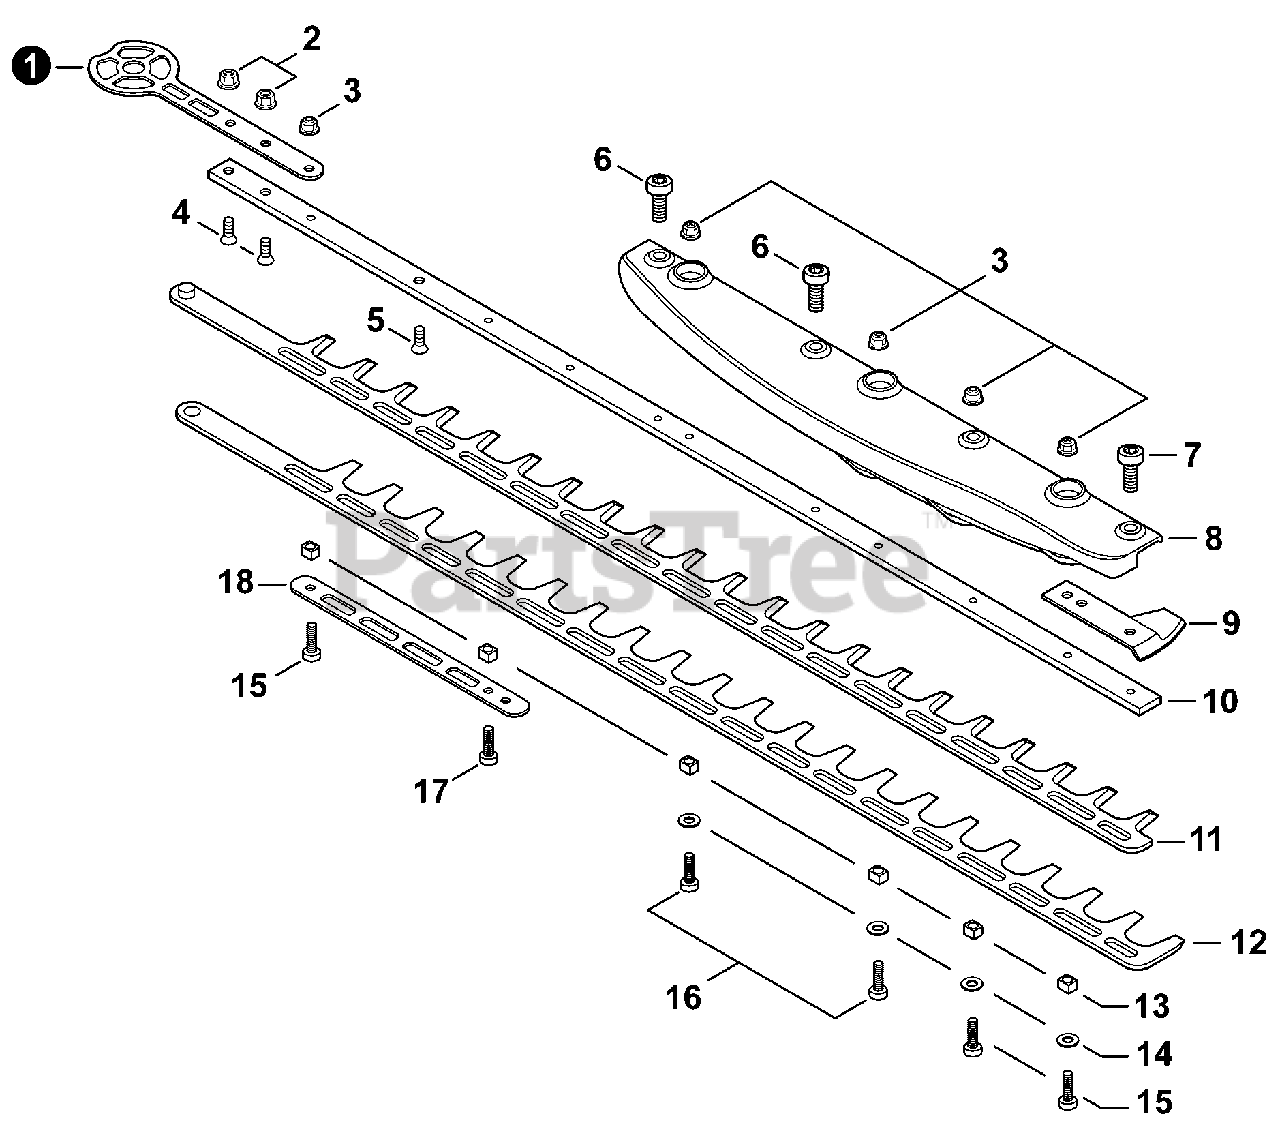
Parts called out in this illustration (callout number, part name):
2	NUT, FLANGE M6
3	NUT, FLANGE M5
4	BOLT 6×30
5	BOLT 6×25
6	BOLT, TORX 5×8
7	BOLT, TORX 5×10
8	DEFLECTOR, DEBRIS
9	GUARD, TIP
10	SUPPORT, BLADE 30"
11	BLADE, UPPER 30"
12	BLADE, LOWER 30"
13	COLLAR 5
15	BOLT, TORX 5×25
16	BOLT, TORX 5×20
17	BOLT, TORX 5×30
18	PLATE, EYE
